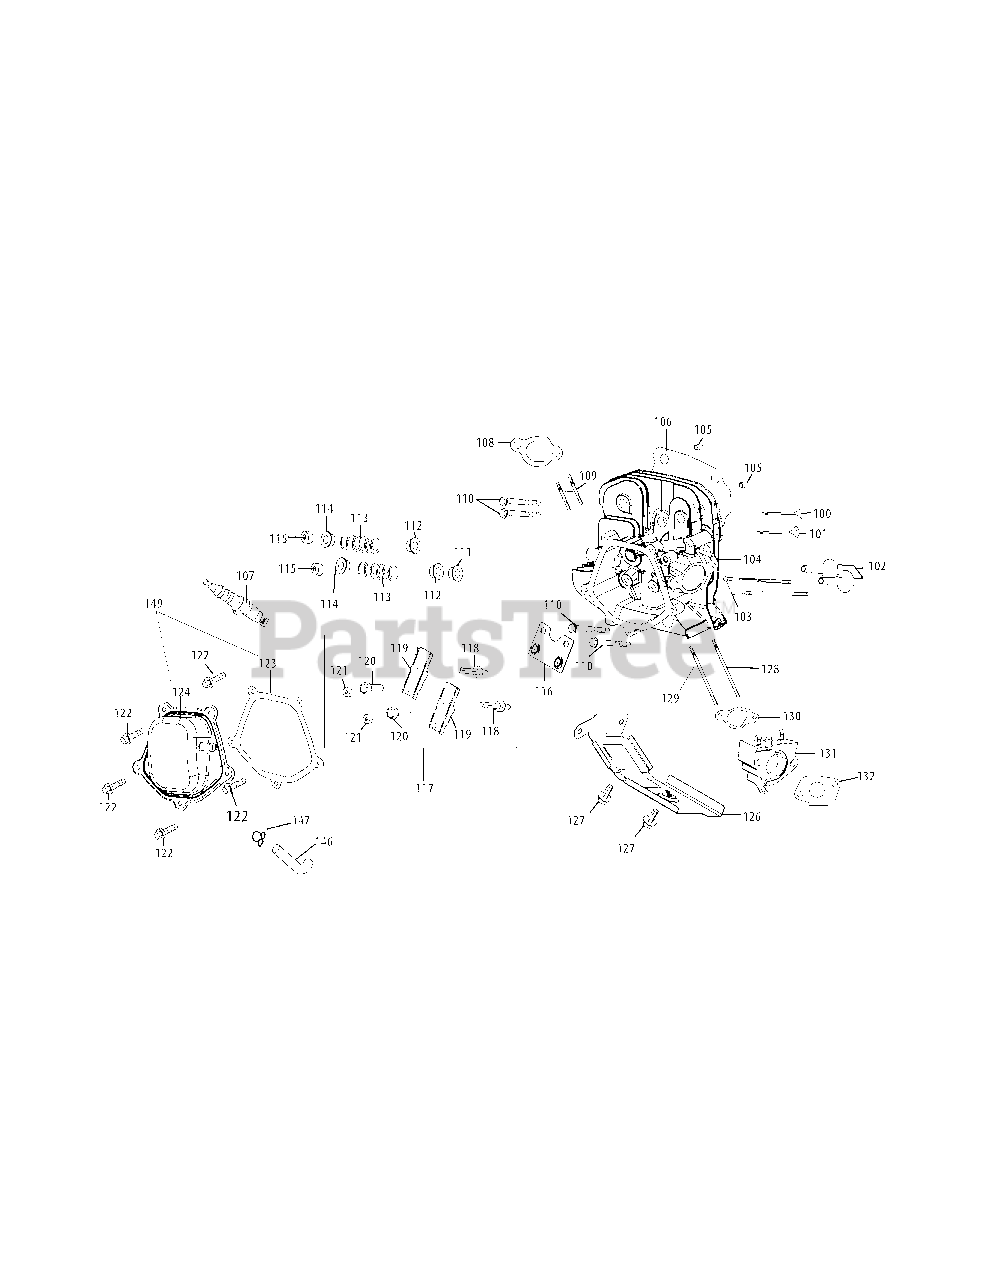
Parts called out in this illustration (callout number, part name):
100	Valve Kit
101	Valve Kit
102	Tappet
103	Push Rod (2X)
104	Cylinder Head Ass'y
105	Dowel Pin, 12 × 20
106	Gasket, Cylinder Head
107	Spark Plug
108	Exhaust Pipe Gasket
109	Stud, M8 x 48.5
109	Muffler Stud Ass’y
110	Bolt, M10 × 1.25 × 87
111	Intake Valve Seal
112	Valve Spring Retainer
113	Valve Spring
114	Retainer, Ex.Valve Spring
115	Adjuster, Exh Valve
116	Push Rod Guide
117	Rocker Arm Ass’y
118	Bolt, Pivot
119	Rocker Arm
120	Adjusting Nut, Valve
121	Nut, Pivot Locking
122	Valve Cover Bolt
123	Valve Cover Gasket
124	Valve Cover
126	Cylinder Baffle
128	Stud, M6 x 8 x 98
129	Stud, M6 x 8 x 118
130	Carburetor Insulator Gasket
131	Carburetor Insulator Plate
132	Carburetor Gasket
146	Breather Hose
149	Valve Cover Kit
